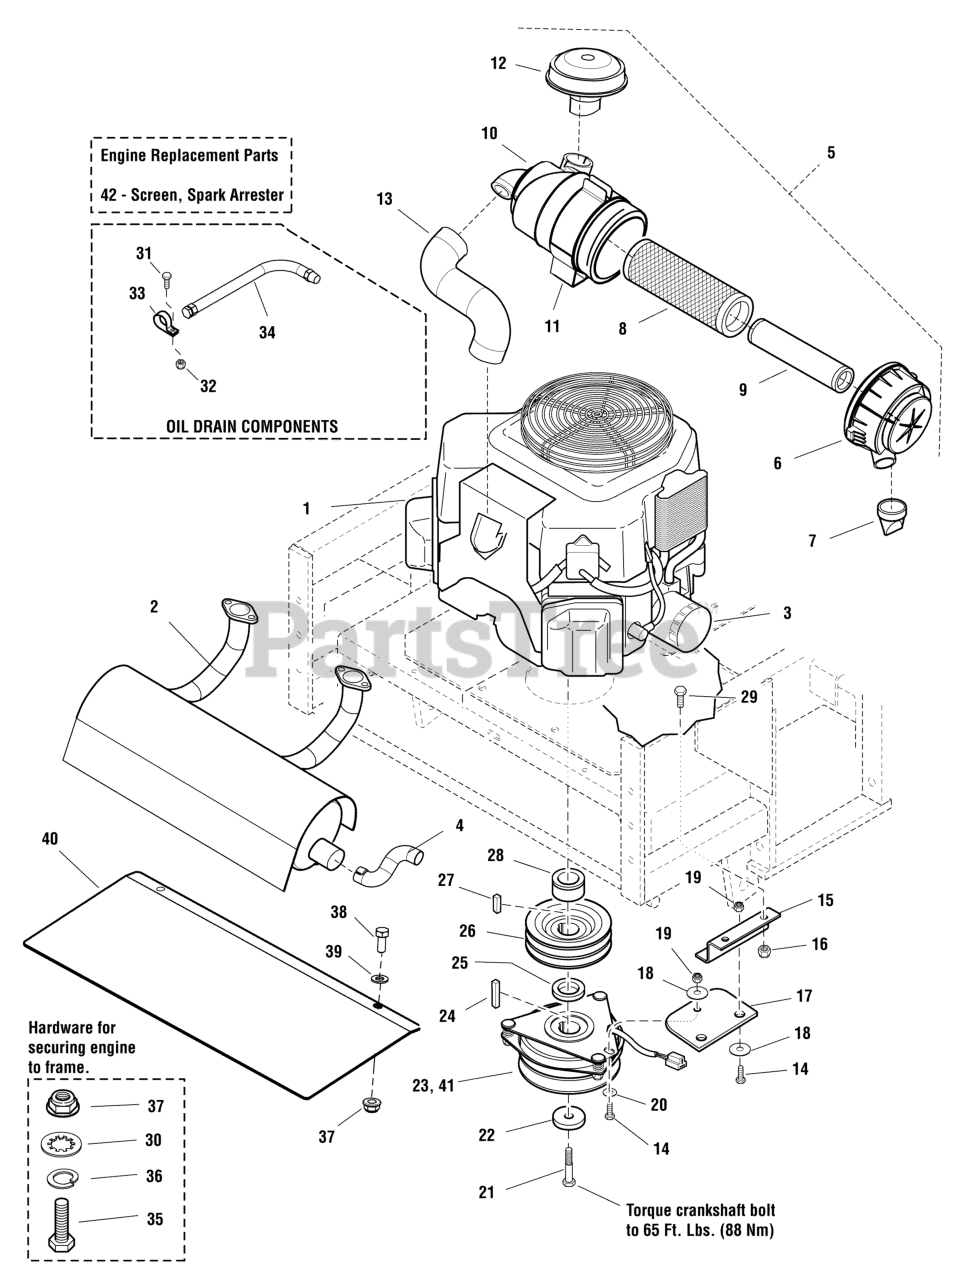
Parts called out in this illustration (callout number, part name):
1	ENGINE
3	OIL FILTER
5	KIT, 5.5 HD AIR CLEANER
7	DUST VALVE
8	PRIMARY PAPER ELEMENT
9	SECONDARY ELEMENT
11	HOUSING MOUNT BRACKET
12	RAIN COVER
13	INLET HOSE
14	BOLT, 5/16-18 X 1" GD5 YZ
15	ANCHOR, CLUTCH - BLK
16	NUT, 3/8-16 HEX NYLOCK FLANGE
17	CLUTCH ANCHOR PAD
18	WASHER, 3/8" FENDER
19	NUT, 5/16-18 HEX NYLOCK FLANGE
20	WASHER, 5/16" SAE
21	BOLT, CRANKSHAFT, 7/16"X2-1/4
22	SPACER, .45 X 1.88 X .38
23	CLUTCH, OGURA, 250 ft lbs - 1.13"
24	KEY, 1/4 SQ X 2
25	SPACER, 1.13 X 2.00 X .19
26	PULLEY, CRANKSHAFT
27	KEY, 1/4 SQ X 1
28	SPACER, 1.13 X 1.75 X 1.03
29	BOLT, 3/8-16 X 1" GD5 CZ
30	WASHER, 5/16" INT. TOOTH LOCK
31	BOLT, 1/4-20 X 1" GD5 CZ
32	NUT, 1/4-20 HEX NYLOCK FLANGE
33	CLAMP, VINYL
34	HOSE, OIL DRAIN
35	BOLT, 5/16-18 X 1-1/2" GD5 YZ
36	WASHER, 5/16 LOCK CZ
37	NUT, 5/16-18 HEX NYLOCK FLANGE
38	BOLT, 5/16-18 X 3/4 GD5
39	WASHER, 5/16" SAE
40	PLATE, HEAT SHIELD, 3100ZK - RED
41	CLUTCH, WARNER,# 5218-158
